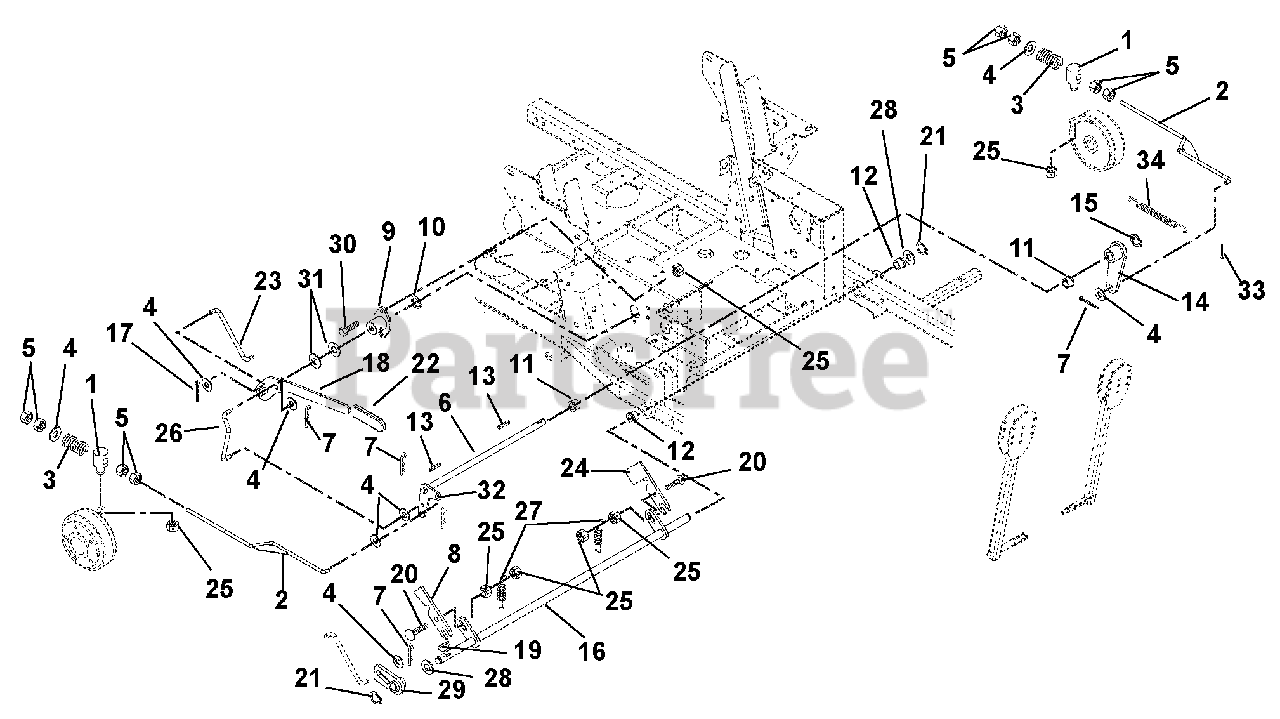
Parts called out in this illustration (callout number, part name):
1	Pivot, Brake Rod
2	Rod, Brake 200 XDZ LPG
3	Spring, Compression .142 x .710 x 1.75
4	Washer, Flat Steel .406 x .812 x .065
5	Nut, Hex .38-16
6	Shaft, Brake Cross
7	Pin, Hair
8	Slide, Interlocking Brake
9	Bushing, Flange
10	Ring, Retaining External .625 x .05
11	Bushing, Flange Nylon .762 x 1.00 x .58 x 1.48
12	Bushing, Flange .515 x .75 x .745 x 1.00
13	Key, Square .188 x 1.00 x .188
14	Arm, Brake Left Hand
15	Ring, Retaining External .625 x .050
16	Weldment, Mechanical Brake
17	Pin, Cotter External .09 x .75
18	Weldment, Brake Handle
19	Key, Woodruff .13 x .63
20	Bolt, Round Head Square Neck .31-18 x 1.25 Grade 5
21	Ring, Retaining External .50 x .05
22	Grip, Handle
23	Linkage, Brake Actuating
24	Interlock, Safety Switch
25	Nut, Locking, Top Flange .31-18
26	Linkage, Brake Actuating
27	Spring, Tension .063 x .44 x 1.56
28	Washer, Flat Steel .505 x 1.00 x .062
29	Weldment, Parking Brake Hub
30	Bolt, Hex .31-18 x .75 Grade 5
31	Washer, Flat Steel .630 x 1.250 x .062
32	Weldment, 200 Brake Actuating Arm
33	Pin, Cotter .12 x .75 Extended Prong Square Cut
34	Spring, Extension
